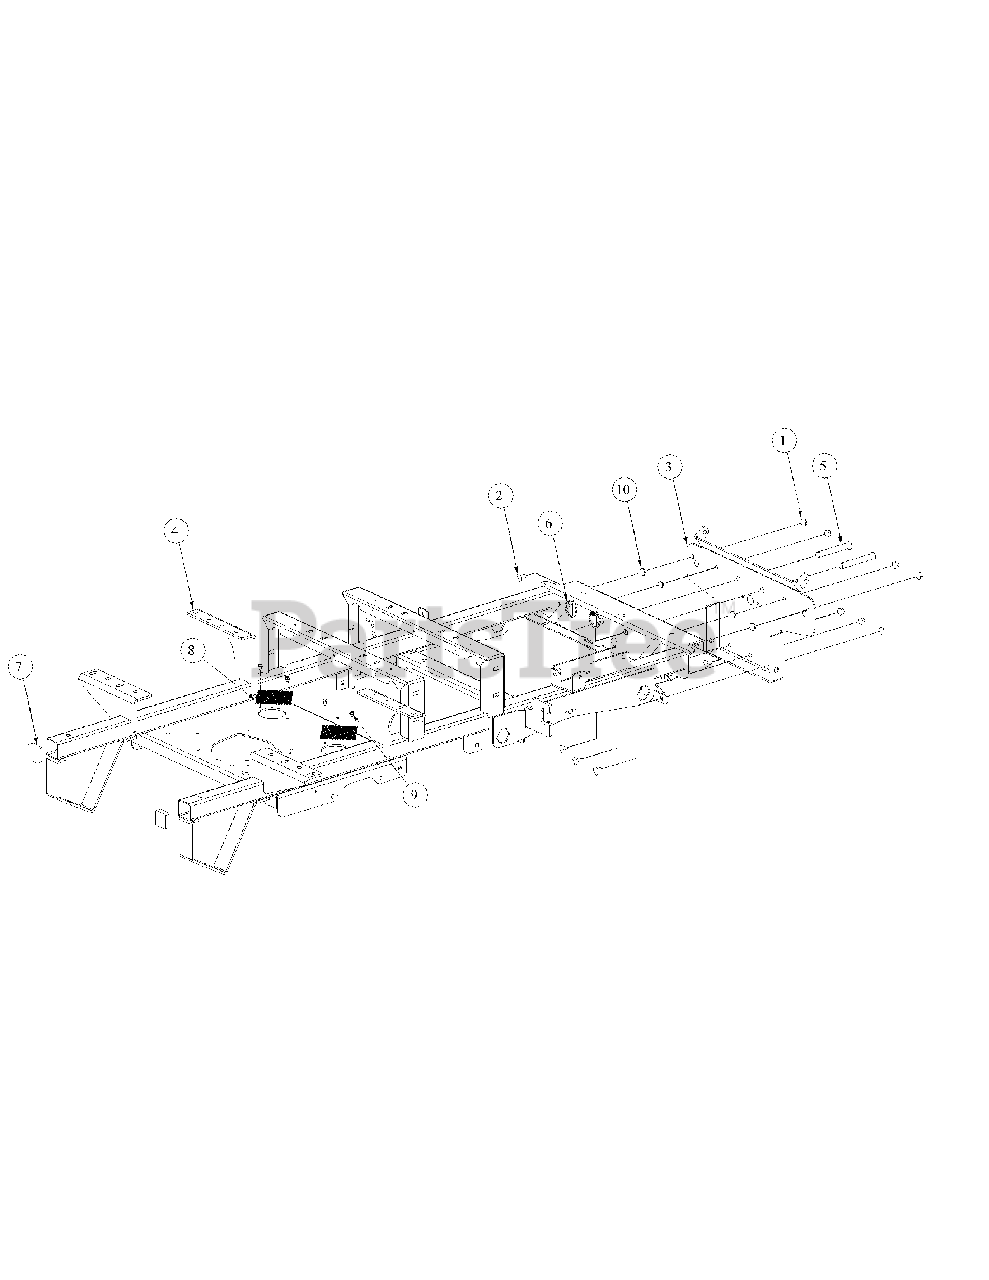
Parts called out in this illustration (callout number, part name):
1	Hex Nut, 3/8-16 Flange Lock
2	Carriage Bolt, 3/8-16 x .75 Long
3	Bracket Assembly, Frame, Front
4	Frame Assembly
5	Clevis Pin, .625Dia x 4.375 Long
6	Linch Pin, 3/16 Dia.
7	Plug, Square Tube
8	Cover, Hydro Fan
9	Screw, TT, 1/4-20, 0.5
10	Push Retainer, 3/8
